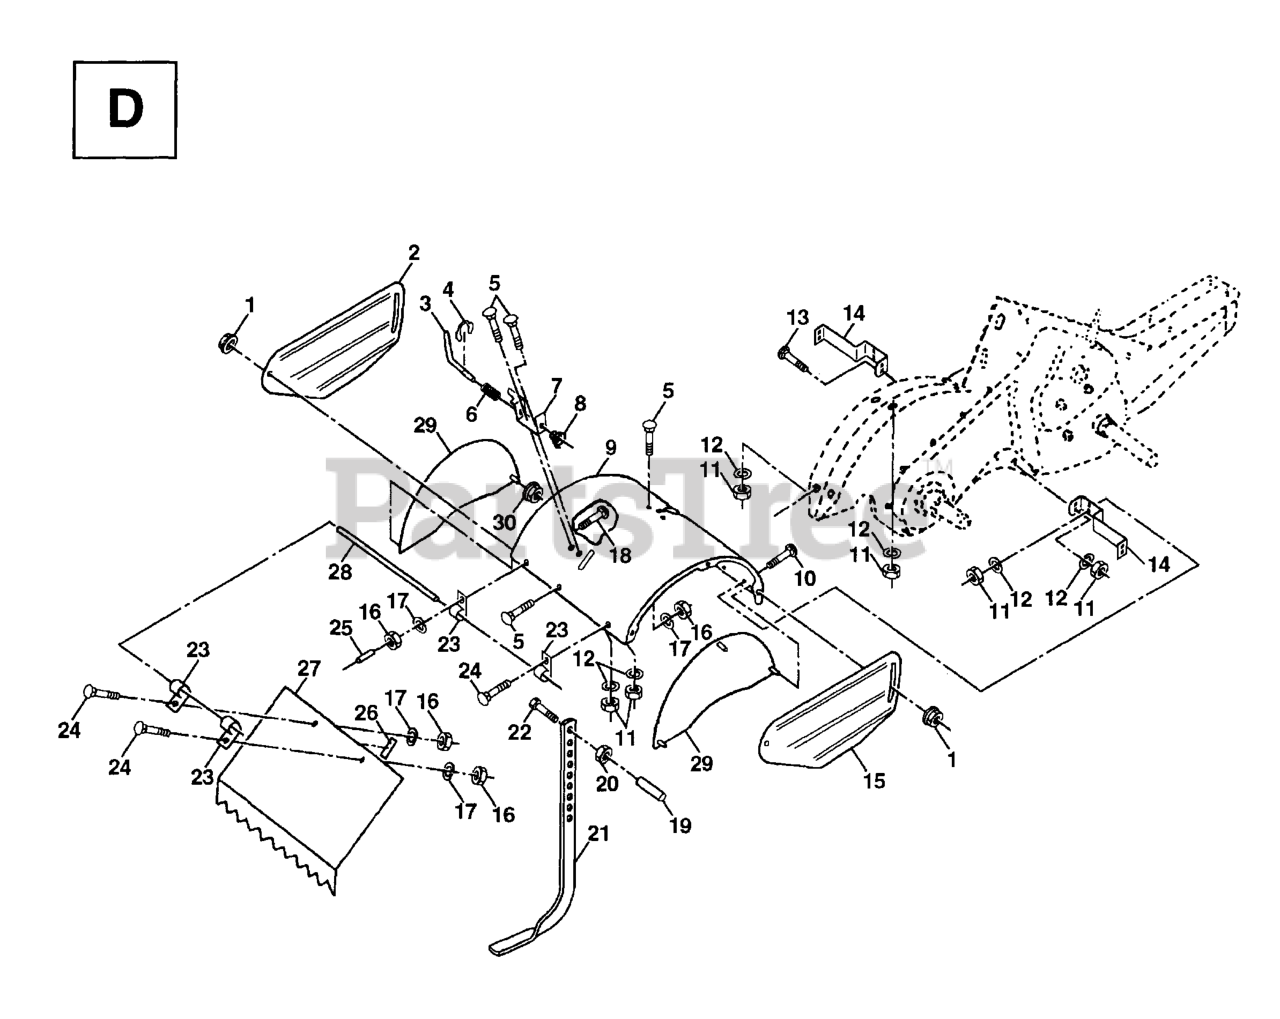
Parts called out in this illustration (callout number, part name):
1	NUT
2	SHIELD SIDE OUTER LH
3	STAKE PIN TI
4	KLIP RING TI
5	RP BOLT 5/16-18 X3/4 ZN/YEL GR
7	BRACKET.LATCH.STAKE.3.20.BLACK
8	SPRING CRT
9	SHIELD
12	WASHER.LOCK.HVY.HLCL.SPR.5/16
13	BOLT.CARRIAGE.5/16-18
14	BRACKET.TINE.SHIELD.TILLER.BLA
15	SHIELD SIDE OUTER RH
16	NUT
17	LOCKWASHER
20	NUT.HEX.3/8-16UNC
21	STAKE.DEPTH.16.CRT.BLACK
22	BOLT.375-16
25	VINYL CAP TI
26	PAD IDLER TI
27	SHIELD LEVELING
28	PIN.HINGE.TILLER
29	SIDE SHIELD
30	LOCKNUT-FLANGE 5/16-18
